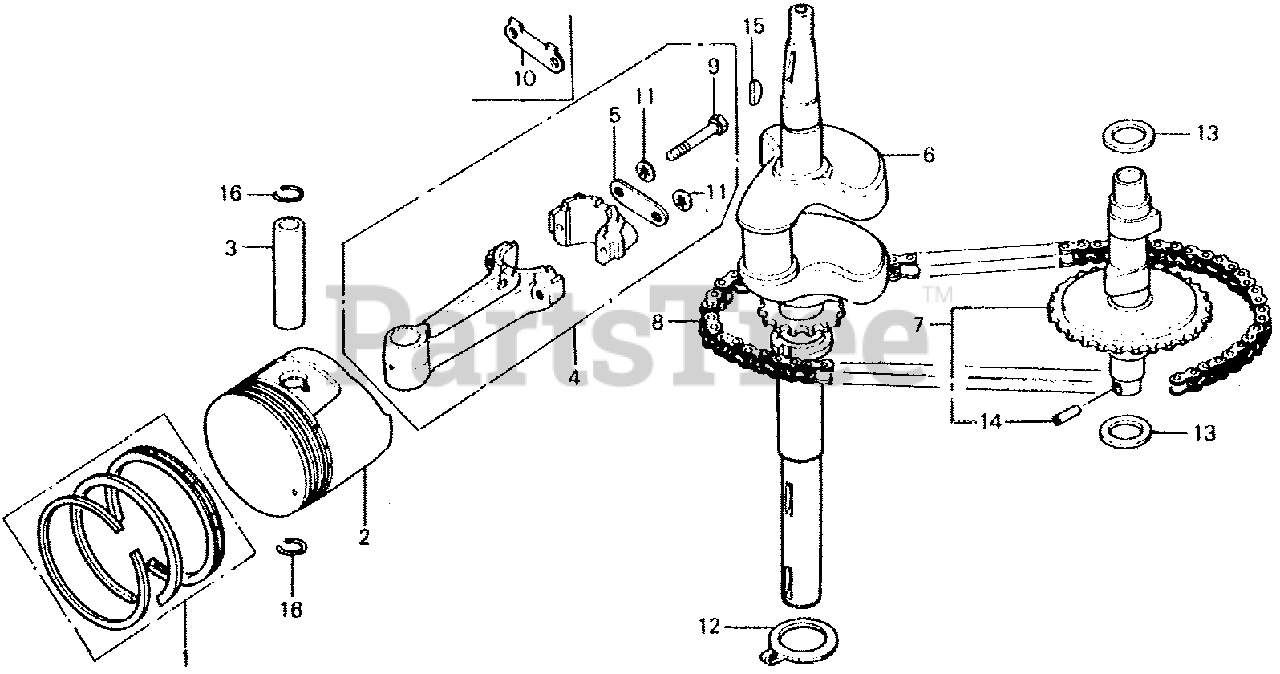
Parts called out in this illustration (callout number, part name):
1	RING SET, PISTON (STD)
1	RING SET, PISTON (OS 0.25) (Honda Code 0635052). (OS)
1	RING SET, PISTON (OS 0.50) (Honda Code 0635060). (OS)
1	RING SET, PISTON (0.75) (OS)
2	PISTON (STD)
2	PISTON (OS 0.25) (OS)
2	PISTON (OS 0.50) (OS)
2	PISTON (0.75) (OS)
3	PIN, PISTON
4	ROD ASSY., CONNECTING
4	ROD ASSY., CONNECTING (Honda Code 0905620). (UNDER SIZE)
4	ROD ASSY., CONNECTING (Honda Code 0871566). (US 0.25)
5	WASHER A, CONNECTING ROD
5	WASHER, CONNECTING ROD
6	CRANKSHAFT (N1)
7	CAMSHAFT ASSY.
8	CHAIN, CAM
8	CHAIN, CAM (Honda Code 0965012). (NOT AVAILABLE)
9	BOLT, CONNECTING ROD (6MM)
9	BOLT, CONNECTING ROD (6MM) (Honda Code 0809145). (NOT AVAILABLE)
9	BOLT, CONNECTING ROD (7MM)
10	WASHER B, CONNECTING ROD
11	WASHER, LOCK (6MM) (Honda Code 0809160). (N/A: SEE ASSEMBLY)
11	WASHER, LOCK (7MM)
12	WASHER, THRUST (35MM)
13	WASHER, THRUST (18MM)
14	PIN, SPRING (2.5X16)
15	KEY, SPECIAL WOODRUFF (25X18)
16	CLIP, PISTON PIN (15MM)
